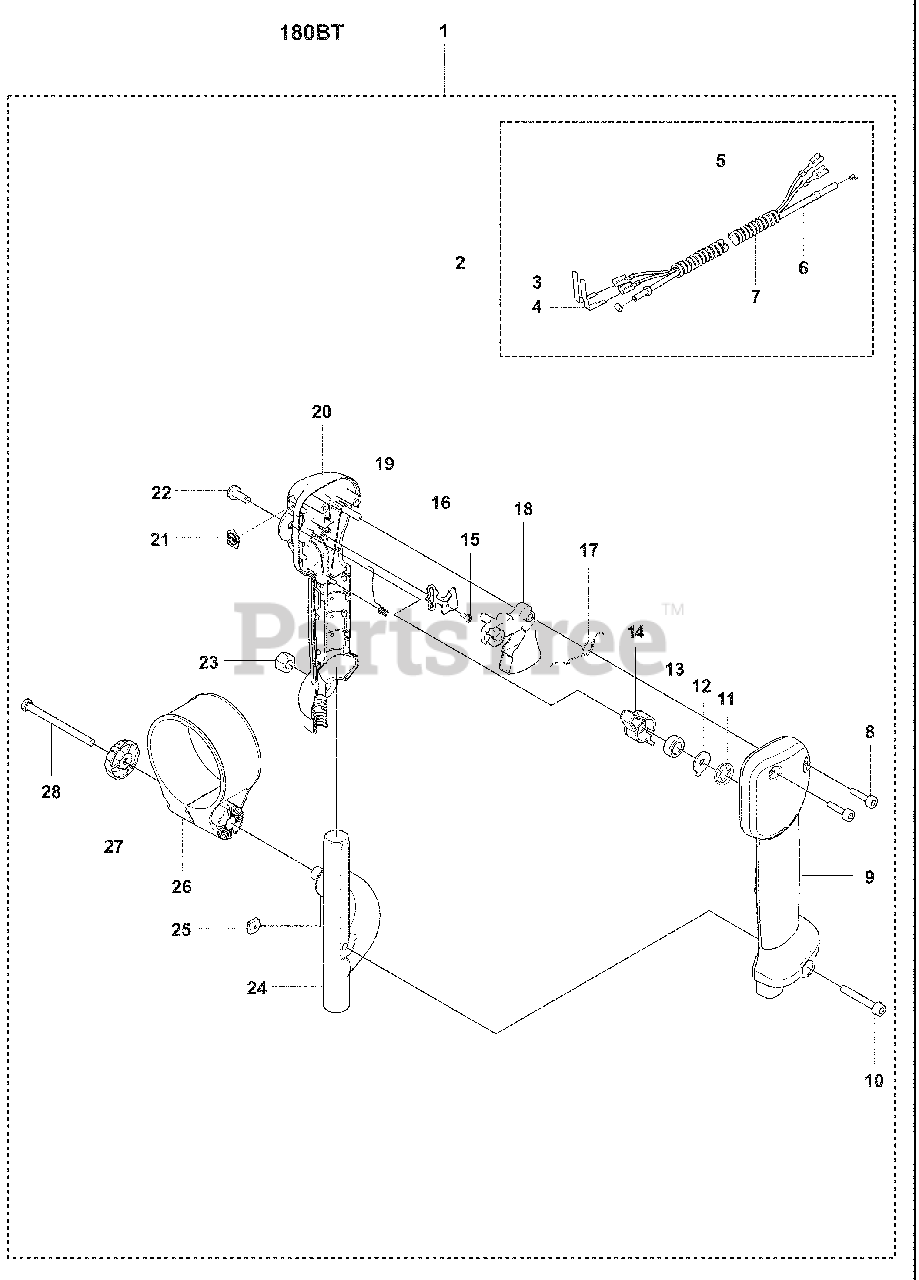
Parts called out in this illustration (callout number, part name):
1	HANDLE ASSY
2	Wiring Assembly, 380BTS
3	Contact Spring
4	Contact Spring
9	Right Half Handle
10	Screw, Ihscfm M5 X 35 10.9 ZP
13	Spring, Rubber
14	Stop Lever
20	Left Half Handle
25	Square Nut
26	HOLDER TH
27	Air Filter Cover Knob
